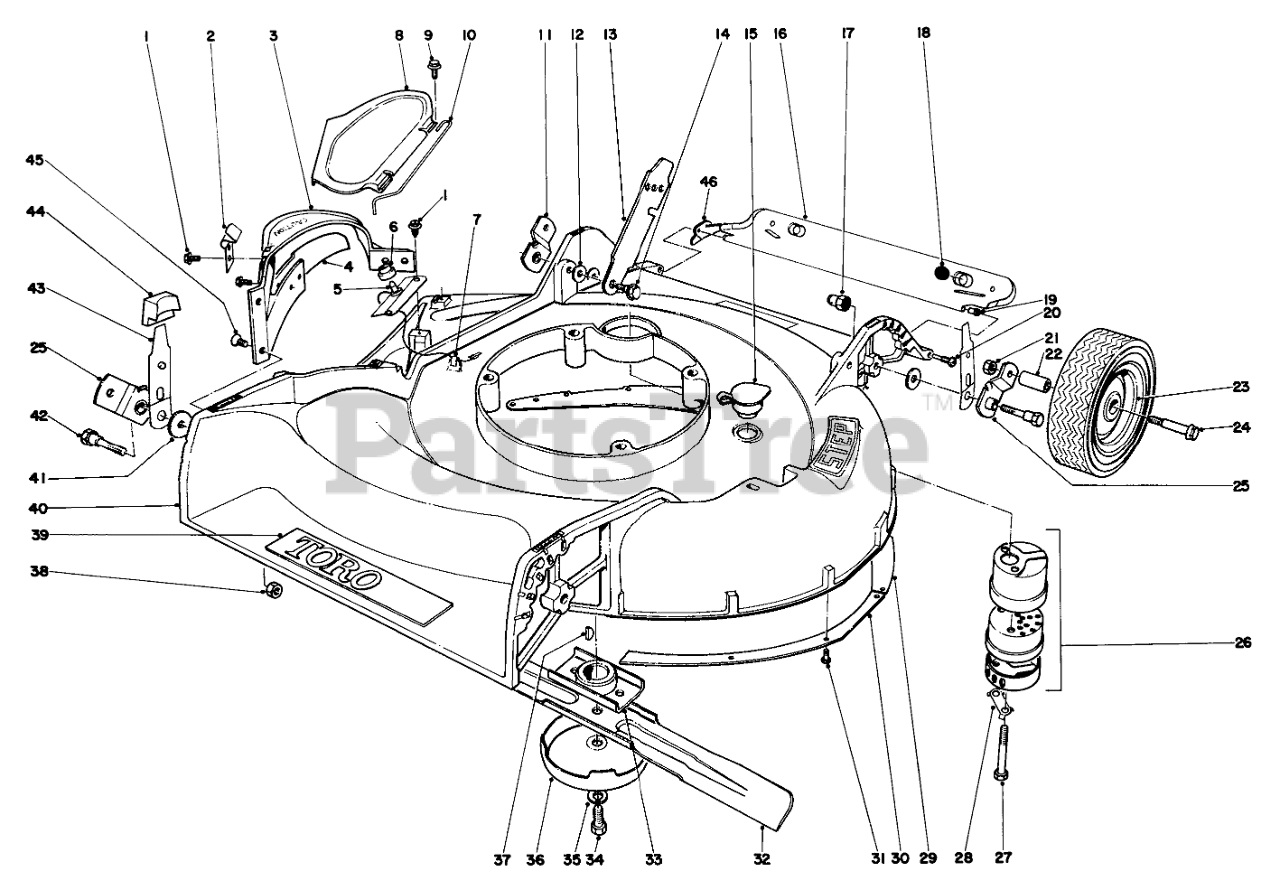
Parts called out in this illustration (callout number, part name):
2	Latch
3	Deflector (Incl. Ref. Nos. 1-4)
4	DefIector Bar
5	Deflector Switch & Wire (Incl. Ref. No. 6)
6	Boot Switch
8	Deflector Cover
9	SCREW
10	Hinge Spring
11	Pivot Arm
12	SPACER
13	Latch
14	SCREW-SHOULDER
15	WASHOUT PLUG
16	Rear Safety Shield (Incl. Ref. Nos. 18 & 19)
17	HANDLE PIVOT NUT
18	SKID BUTTON
19	SAFTEY SHIELD BUSHING
20	SAFTEY SHIELD SCREW
21	Nut
22	Bushing
23	Wheel Assembly
25	Pivot Arm
26	Muffler (Incl. Ref. Nos. 27 & 28)
27	SCREW-HH
28	CLIP - LOCKING
29	Main Skirt
30	Secondary Skirt
32	Blade
33	BLADE RETAINER WA
34	SPECIAL SCREW
35	WASHER-LOCK
36	AntiScalp Cup
37	KEY-WOODRUFF
38	Nut
39	Toro Emblem
40	Housing (Incl. Ref. Nos. 29, 30 & 31)
41	WASHER-PIVOT
42	5/16-18 PIVOT SCREW
43	Spring Arm
44	Knob
45	Screw
46	Restraint R.H.
